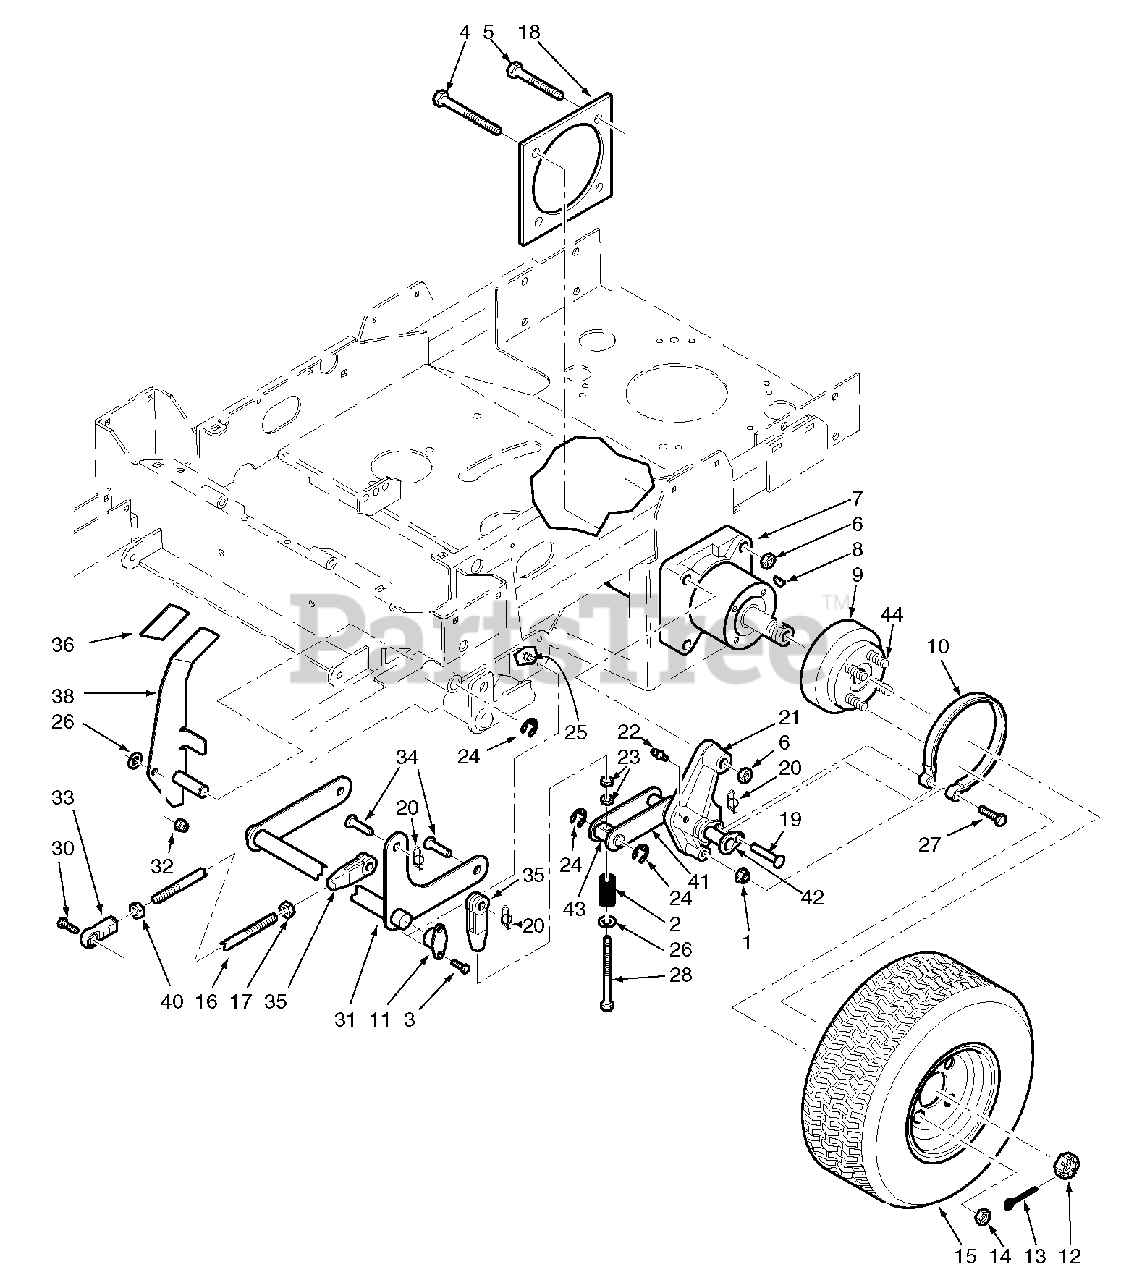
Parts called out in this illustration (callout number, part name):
1	Nut, Serr. Flange 1/2-13
2	Spring
3	Bolt, Hex Head 5/16-18 x 3/4"
4	Bolt, Hex Head 1/2-13 x 3-3/4"
5	Bolt, Hex Head 1/2-13 x 2-1/2"
6	Nut, 1/2-13 Center Lock
7	Wheel Motor, Parker
8	Key, Woodruff 5/16 x 1"
9	Wheel Hub Assembly
10	Brake Band Assembly
11	Bushing, Self Align
12	Nut, Hex Castle 1.0-20 UNEF
13	Cotter Pin, 9/64 x 1-1/2"
14	Lug Nut, 1/2-20
15	Wheel Assembly 24 x 9.5-12 (48" Cutter Deck)
15	Wheel Assembly 24 x 9.5-12 (52" Cutter Deck)
15	Wheel Assembly 24 x 12-12 (61" Cutter Deck)
15	Rim (48" Cutter Deck)
15	Rim (52" Cutter Deck)
15	Rim (61" Cutter Deck)
15	Tire 24 x 9.5-12 (48 &52)
15	Tire 24 x 12-12 (61)
16	Brake Rod Stud, 3/8-24 x 8.125"
17	Nut, 3/8-24 UNF
18	Plate Weldment, Motor Backing
19	Clevis Pin, 3/8 x 1.93"
20	Pin, Rue Cotter 3/8" Dia.
21	Brake Linkage LH
21	Brake Linkage RH
22	Grease Fitting, 1/4-28
23	Nut, 3/8-24 UNF
24	Retaining Ring, .625" Ext.
25	Nut, Elastic Stop 5/16-18
26	Flatwasher, 3/8-.391 x .938 x .105"
27	Bolt, Hex Head 1/2-13 x 2-1/2"
28	Bolt, Hex Head 3/8-24 x 3-3/4"
29	Cotter Pin, 3/32 x 3/4"
30	Bolt, Hex Head 3/8-16 x 1-1/2"
31	Brake Shaft
32	Nut, Elastic Stop 3/8-16
33	Rod End, 3/8-24 LH Thread
34	Clevis Pin, 3/8 x 1.06"
35	Clevis, 3/8-24
36	Grip, Brake Lever
37	Nut, Serr. Flange 3/8-16
38	Brake Lever
39	Bolt, Hex Head 3/8-16 x 2-3/4"
40	Nut, 3/8-24 UNF-2B LH Thread
41	Lever, Brake
42	Shaft Weldment, Pivot
43	Pin, Pivot
44	Bolt, Serr. Flange 1/2-20 x 4.563"
